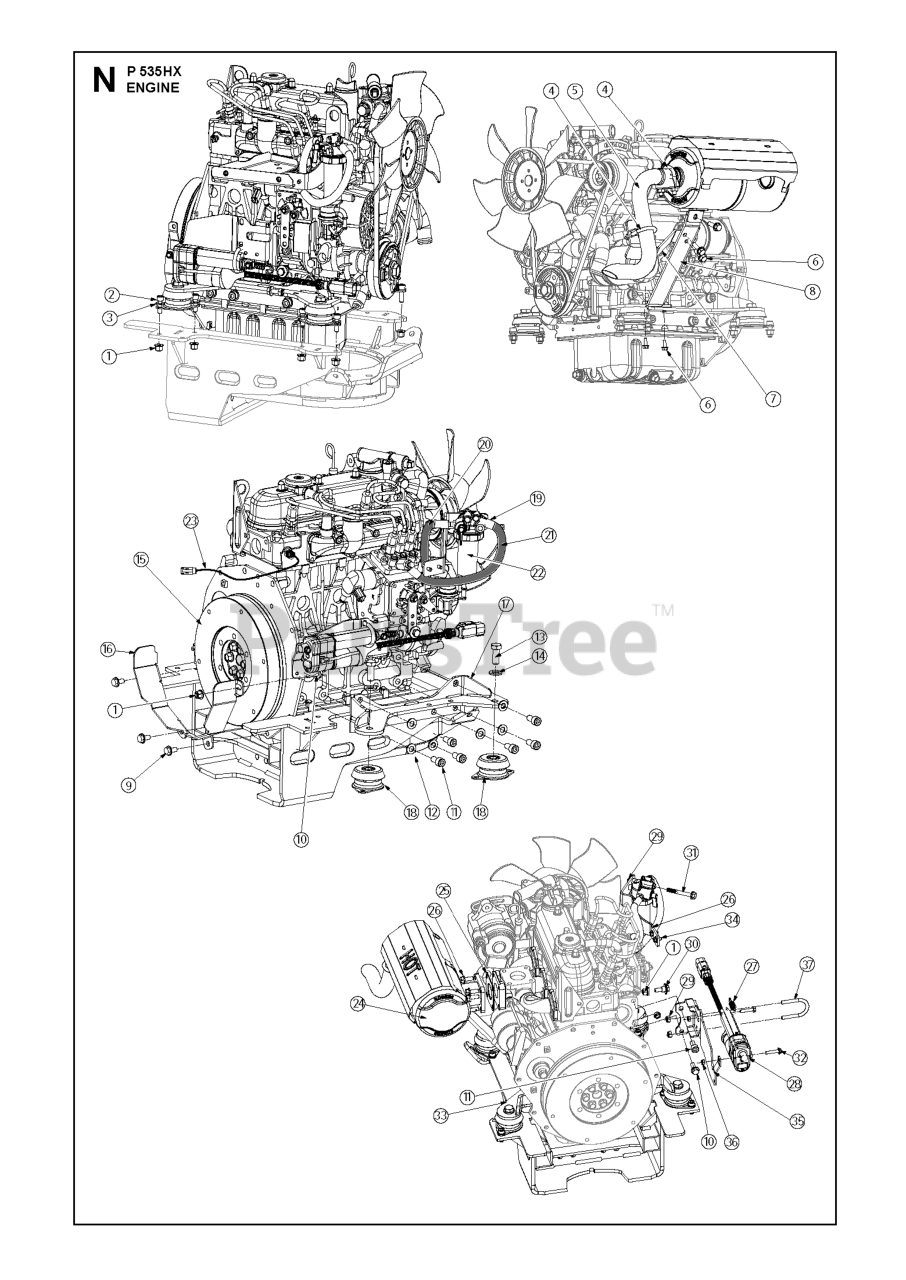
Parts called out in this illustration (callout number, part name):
1	NUT FLANGE
3	WASHER BRB 8.4X17
10	BOLT
12	WASHER
13	Hex Head Capscrew, M12 X 1.75 X 30 DIN933ZP
14	WASHER - M12
19	RP HOSE CLAMP FUEL HOSE
29	LOCKNUT M8
30	COLLAR SCREW
34	SCREW EHHFM
36	LOCKNUT M6
